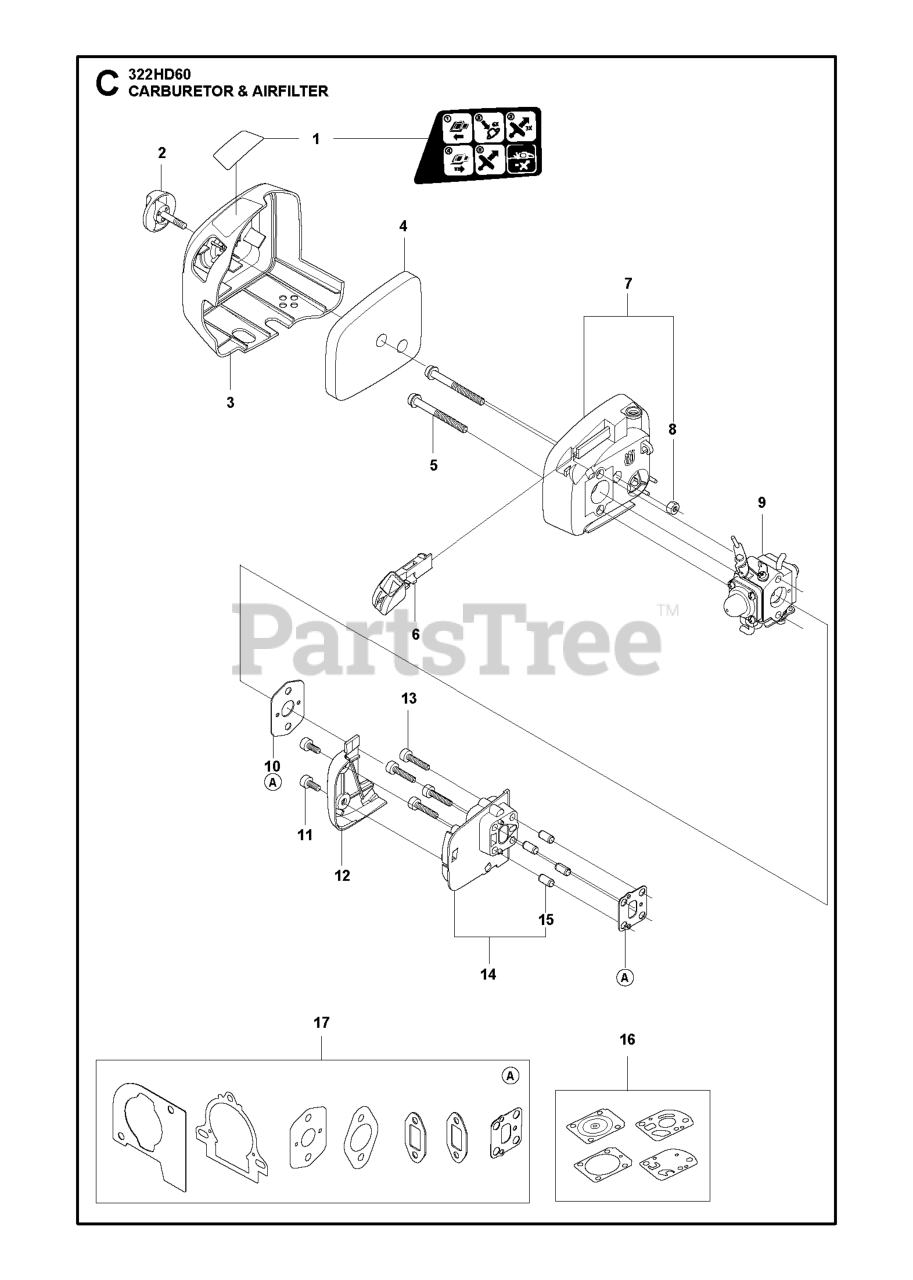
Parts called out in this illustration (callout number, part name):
3	AIR FILTER COVER
4	AIR FILTER
7	FILTER HOLDER ASSY.
9	CARBURETTOR CARBURETTOR ASSY
15	TUBULAR RIVET
16	KIT CARBURETTOR A053
